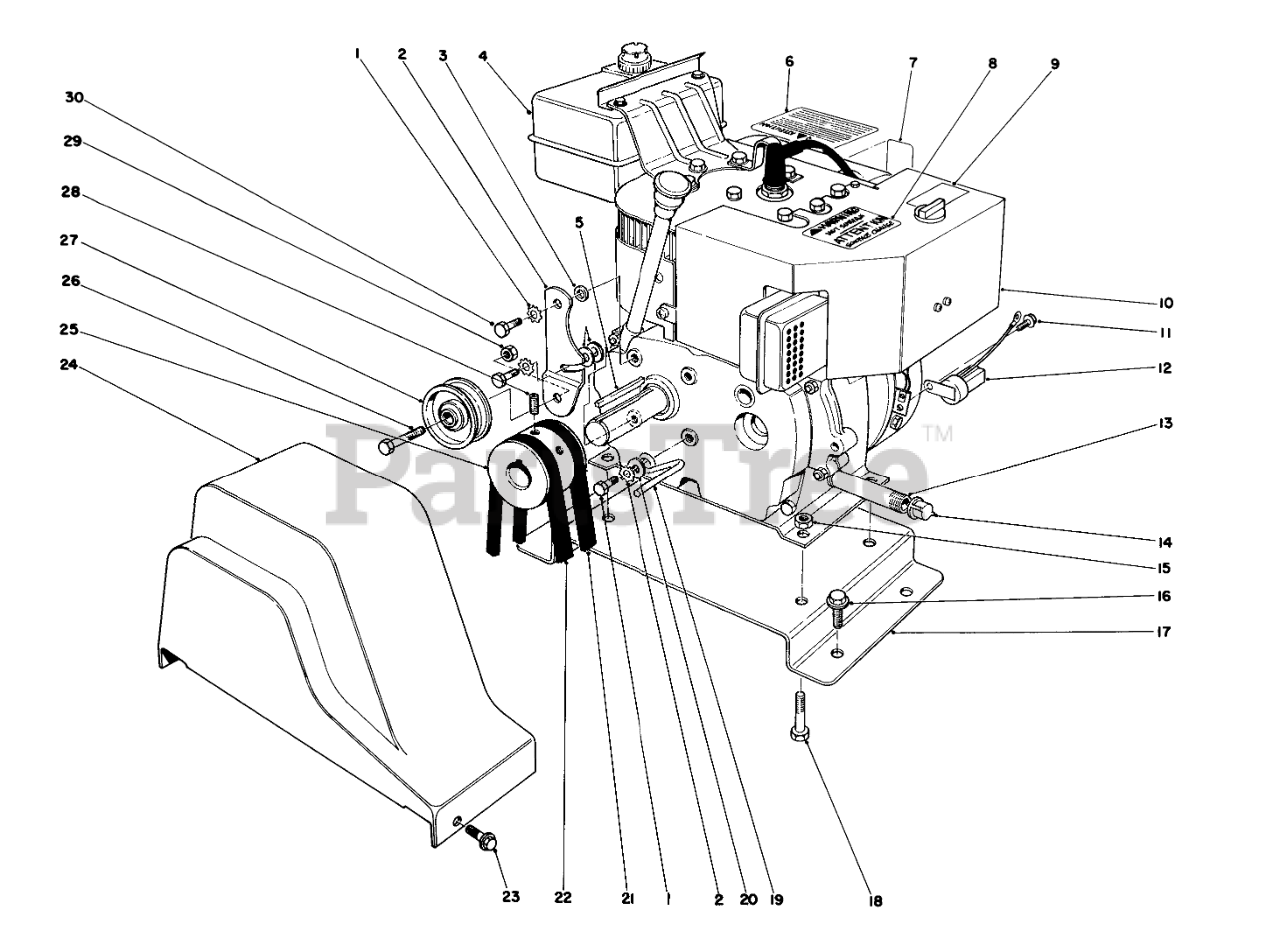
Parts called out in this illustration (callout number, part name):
1	WASHER-LOCK
2	ENGINE IDLER ARM
3	SPACER
4	GAS TANK 2 QT W CAP
6	CAUTION DECAL
7	PRIMER DECAL
8	HOT SURFACE DECAL
9	CHOKE DECAL
10	Engine (Model 38040)
11	SCREW-HWH
12	INTERLOCK MODULE
13	NIPPLE-PIPE
14	CAP-PIPE
15	NUT-LOCK, NI
16	SCREW-HHFTF
17	ENG MTG PLATE R
18	SCREW-HH
19	BELT RETAINER
20	WASHER-PLAIN
21	V-BELT
22	V-BELT
23	SCREW-HWH
24	BELT GUARD
25	ENGINE PULLEY
26	SCREW-HH
27	PULLEY-IDLER
28	Screw-Set
29	NUT-LOCK, NI
30	SCREW-HH
